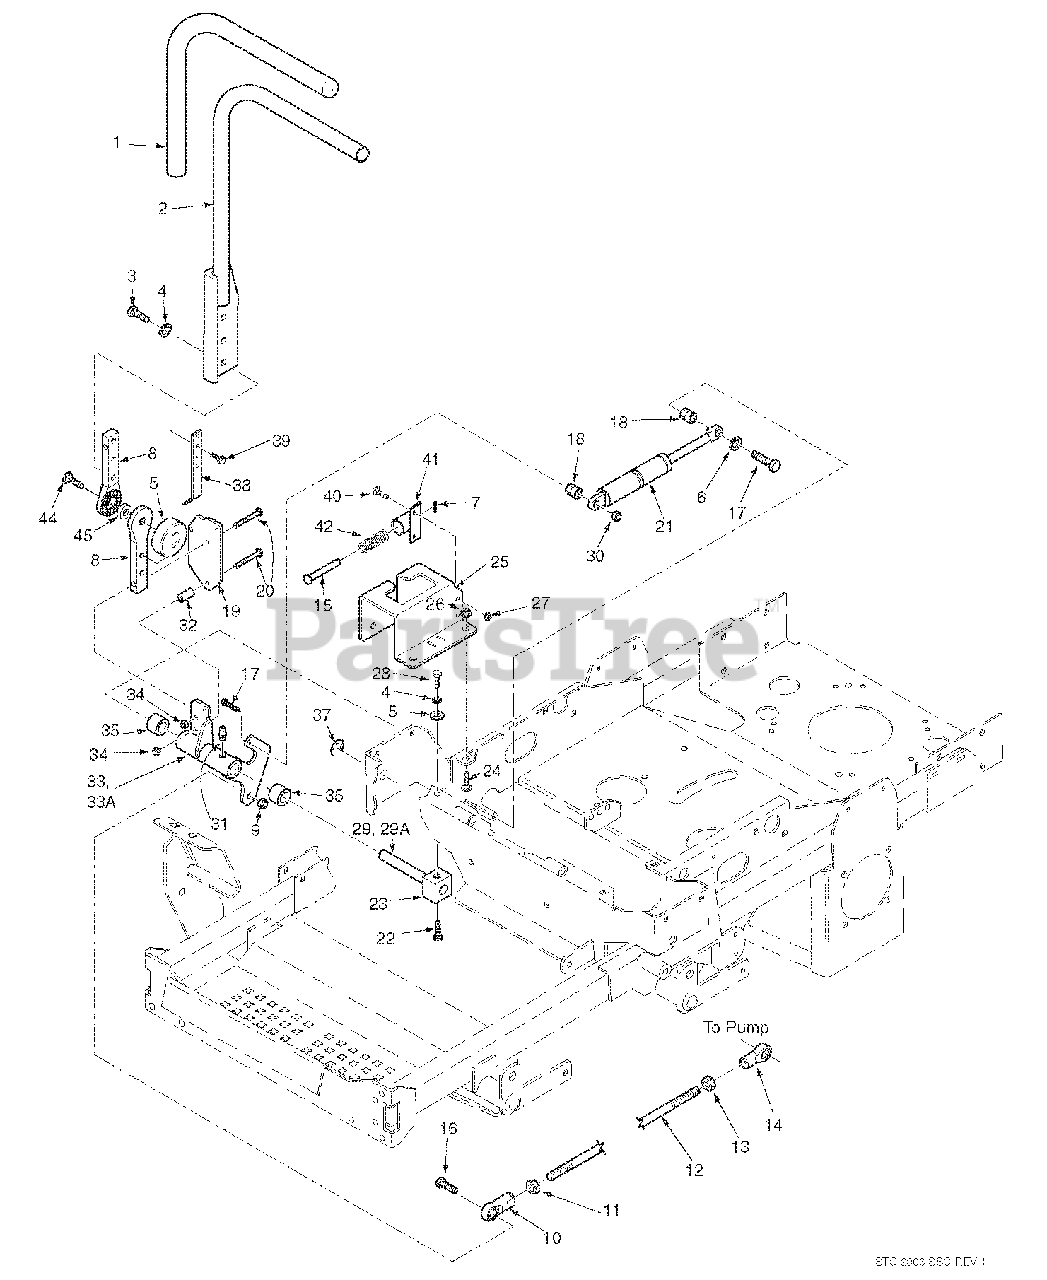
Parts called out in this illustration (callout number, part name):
1	Grip, Control Lever
2	Handle Bar, LH
3	Bolt, Hex Hd. 5/16-18 x 1"
4	Lockwasher, 5/16"
6	Flatwasher, 5/16 (.375 x .875 x .083")
7	Roll Pin, Spring 5/32 x 3/4"
8	Pivot, Control Lever
9	Nut, Elastic Stop 3/8-16
10	Rod End, 3/8-24 RH Female
11	Nut, 3/8-24 RH Thread
12	Rod, Pump Control Linkage
13	Nut, 3/8-24 UNF-2B LH Thread
14	Rod End, 3/8-24 LH Thread
15	Pin Retainer
16	Bolt, Hex Hd. 3/8-16 x 1-1/2"
17	Bolt, Hex Hd. 5/16-18 x 1-3/4"
18	Spacer, Pump Damper
19	Plate, Control Lever
20	Bolt, Hex Hd. 5/16-18 x 2"
21	Gas Damper
22	Bolt, Hex Hd. 3/8-16 x 1"
23	Block, Clamping
24	Bolt, Carriage, 5/16-18 x 3/4"
25	Control Plate - LH w/Decal
26	Nut, Serr., Flng., 5/16-18
27	Nut, Elastic Stop 1/4-20
28	Bolt, Hex Hd. 3/8-16 x 3/4"
29	Shaft, Steering Control
30	Nut, Elastic Stop 5/16-18
31	Grease Fitting, 1/4-28 Self Tap
32	Spacer, Control
33	Control Lever Assy RH
34	Nut, Elastic Stop 5/16-18
35	Bushing
36	Flatwasher, 3/4 (.766 x 1.25 x .059")
37	Retaining Ring, 3/4" Ext.
38	Bracket, Switch Actuator
39	Bolt, Hex Serr. Flng. 5/16-18 x 3/4"
40	Bolt, Carr. 1/4-20 x 3/4"
41	Bracket, Control Return
42	Spring
43	Pin Retainer
44	Bolt, Carriage 5/16-18 x 1-1/2"
45	Rubber Spacer
